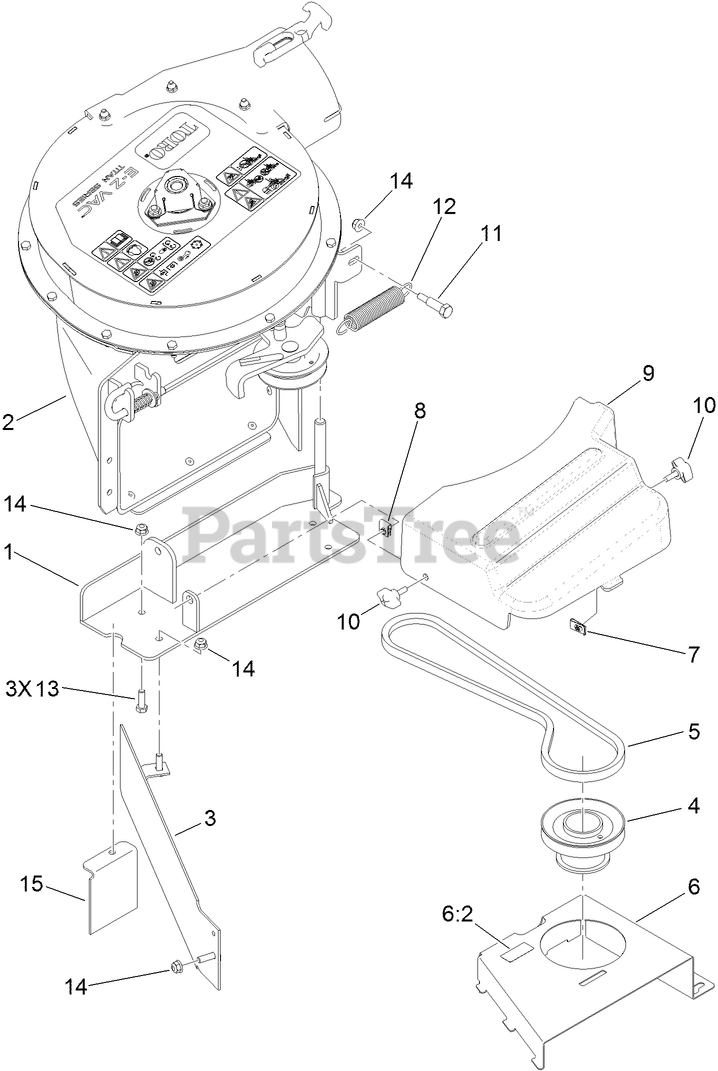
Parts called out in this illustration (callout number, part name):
1	SUPPORT-BLOWER
2	BLOWER HOUSING ASM
4	PULLEY-BAGGER
5	BELT-V
6	COVER ASM
6:2	DECAL-DANGER
7	NUT-SPEED
8	NUT-SPEED
9	COVER-BELT
11	SCREW-SHOULDER, HH
12	SPRING-EXTENSION
13	SCREW-HH
14	NUT-HF, NI
